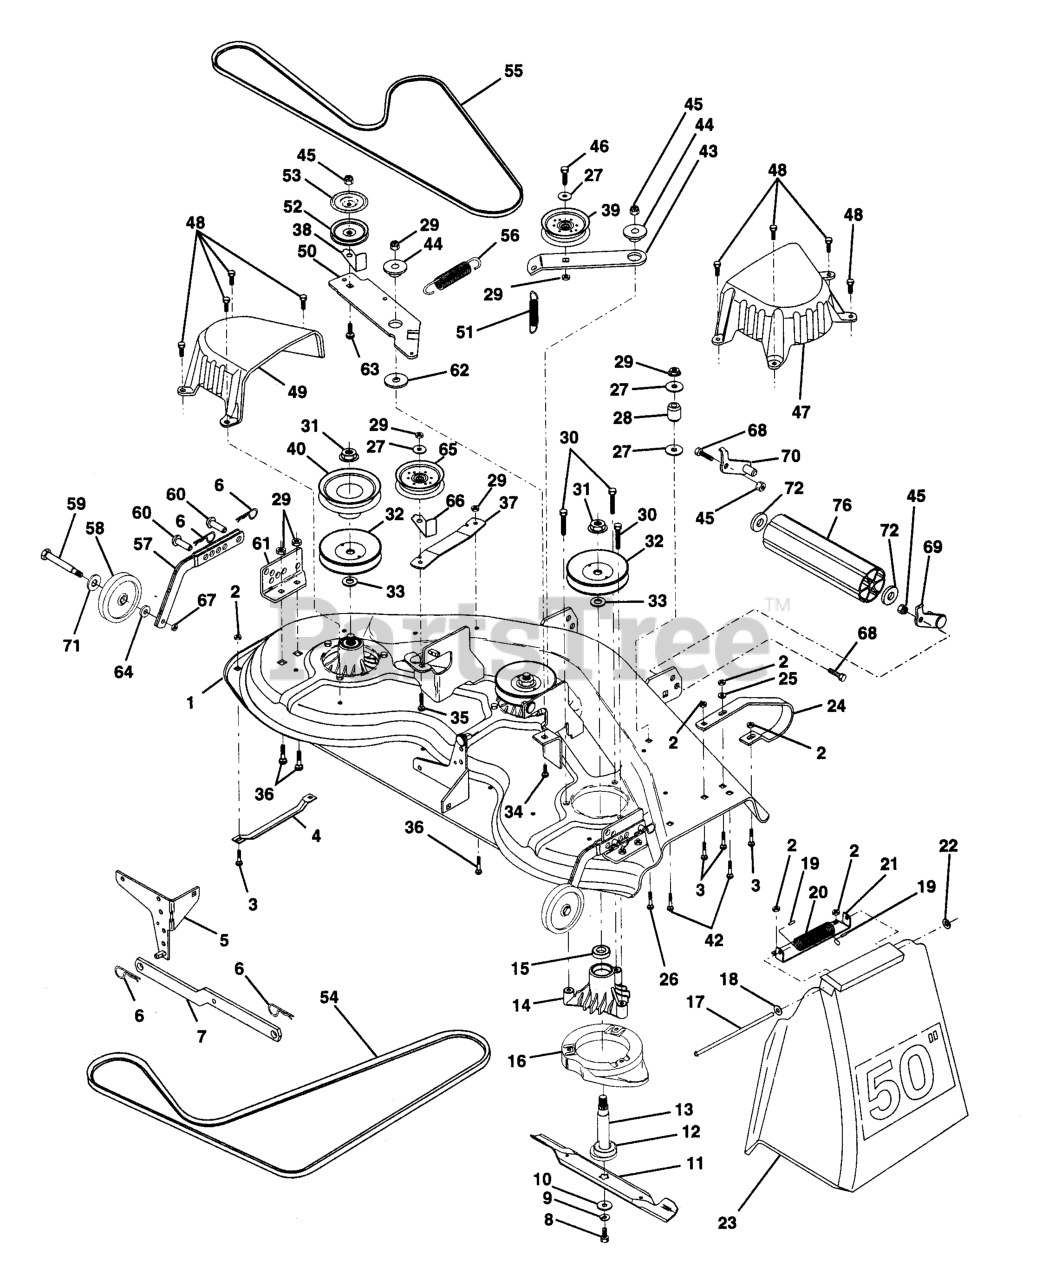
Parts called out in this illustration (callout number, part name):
1	DECK ASM MWR 50VT
2	NUT.71038.31-18.HEX.NYLOCK
3	BOLT.CARR.SQNK.5/16-18UNC.X3/4
4	RUNNER-LH M
5	BRACKET SWAY BAR
6	RETAINER-SPRNG RB
7	REAR SUSP ARM
8	BLADE BOLT
9	LOCKWASHER
10	WASHER.BLADE
11	BLADE.50".HI-LIFT
12	BEARING.BALL.#6204.(MANDREL)
13	SHAFT.ASM.W/BEARING
14	HOUSING.MANDREL.44/46" VENT
16	STRIPPER
17	ROD-HINGE T
18	Washer 11/32 x 5/8 x 16 Ga.
19	CAP-SLEEVE LT
20	SPRING TORSION
21	BRACKET, DEFLECTOR
22	NUT PUSH M
23	SHIELD.DEFLECTOR.MOWER.50"BLK.
25	WASHER M
27	WASHER
28	IDLER SPRING SPACER
29	NUT
30	SCREW
31	NUT
32	MANDREL PULLEY
33	WASHER
34	BOLT.3/8-14X1.25
35	BOLT
36	BOLT D
37	STIFFENER ARM
38	KEEPER
39	FLAT IDLER PULLEY
40	PULLEY.DRIVEN.44"
42	RP BOLT 5/16-18 X3/4 ZN/YEL GR
43	ARM.IDLER.SEC.44"
44	SPACER RETAINER
46	BOLT
47	COVER MANDRELL
48	SCREW.1/4-20X5/8
49	COVER.MANDREL.LH.44"
50	ARM.IDLER.PRIMARY
51	SPRING.SEC.44"VEN
52	PULLEY IDLER
53	SHIELD IDLER
54	V-BELT.PRMRY 46/50 VENT.BLK BK
55	BELT, V GROUND DRIVE 95 25
57	BAR.ASM.GUAGE.WHEEL
58	WHEEL.GAUGE.BLK.4.93
59	BOLT M
60	PIN.CLEVIS
61	BRACKET.GUAGE.WHEEL
62	HARDENED WASHER
63	BOLT.3/8-16X1.50
64	WASHER.5/16.FLAT.STE.STD.
65	IDLER-FLAT T
66	KEEPER
67	LOCKNUT
68	BOLT
69	BRACKET RH (B)
70	BRACKET LH (A)
71	Washer 17/32 x 15/16 x 12 Ga.
72	Washer 17/32 x 7/8 x 16 Ga.
76	NOSE ROLLER
